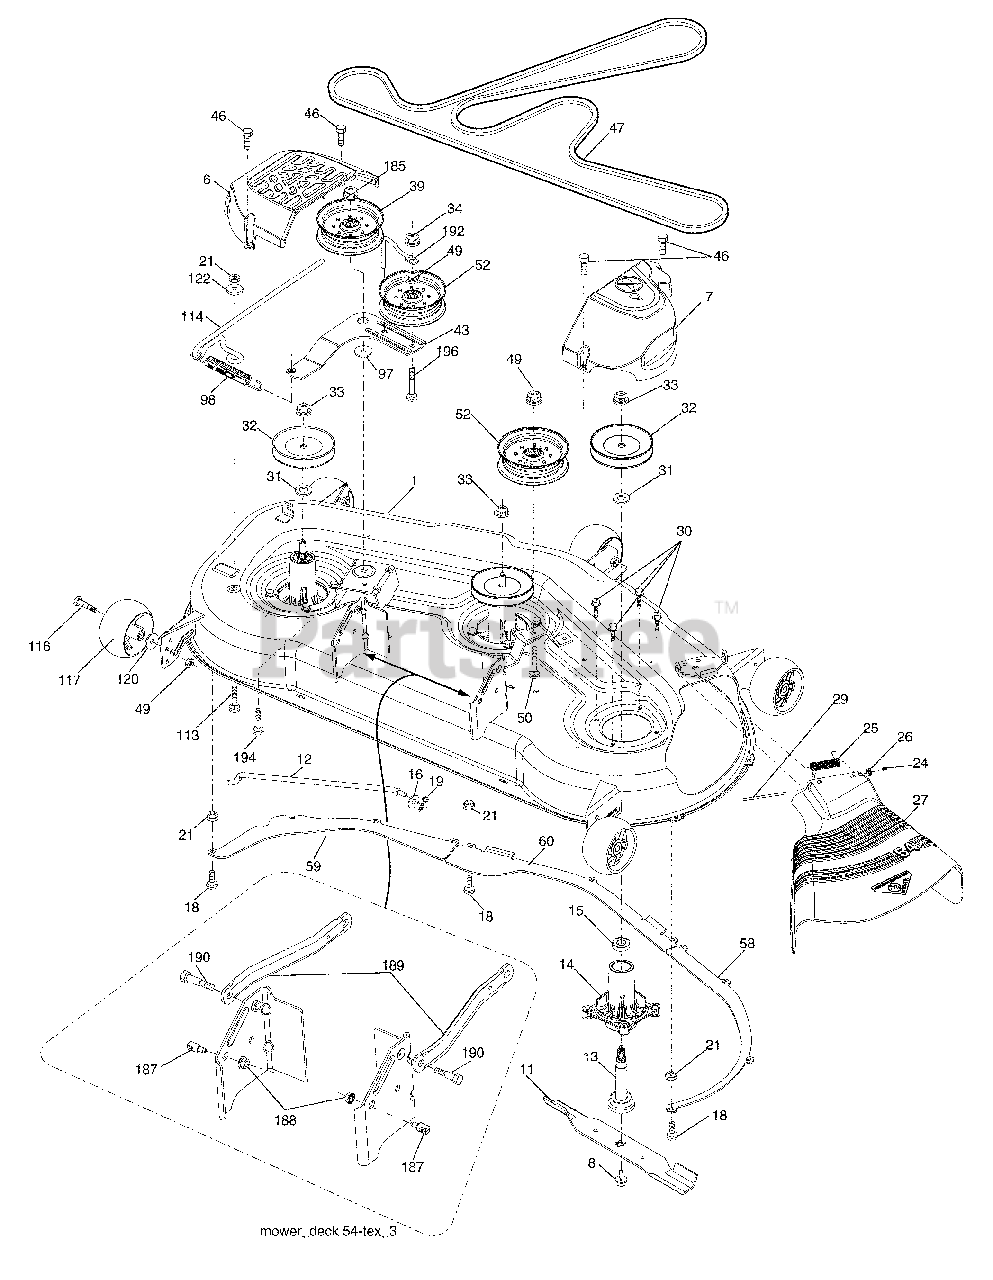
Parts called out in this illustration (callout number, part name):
1	Deck Weldment Mower
6	Cover Mandrel LH
7	Cover Mandrel RH
8	Bolt 7/16 Asm. Blade
11	Blade High Lift
12	Bar Anti-Sway
13	Shaft Asm. w/Lower Bearing
14	Housing, Mandrel
15	Bearing, Ball, Mandrel
16	Washer 3/8
18	Bolt RdHd 5/16-18 unc x 5/8
19	Pin Cotter 5/16 Bowtie
21	Nut, Crownlock 5/16-18 unc
24	Cap Sleeve
25	Spring, Torsion
27	Defl ector Shield
29	Rod, Hinge
30	Screw, Thdroll Washer Head
31	Washer, Spacer Mower Vented
32	Pulley, Mandrel
33	Nut, Flg. Top Lock
34	Nut Crownlock 3/8-46 UNC
39	Pulley, Idler, Stationary LH
43	Arm, Idler
46	Screw, Thdroll. 1/4-20 x 5/8
47	Belt Deck Drive
49	Nut, Lock Flg. 3/8-16 unc
50	Bolt Carriage 3/8-16 x 2 Gr. 5
52	Pulley Idler
58	Baffl e Right
59	Baffl e Left
60	Baffl e Center
97	Washer Hardened
98	Spring Drive
113	Bolt Rdhd Sqnk 5/16-18 x 3/4
114	Rod Tension Relief
116	Bolt, Shoulder
117	Gauge Wheel
120	Washer 13/32 x 1-1/4 x 12 Ga.
122	Bushing Tension Relief
185	Nut Lock Flange 7/16-14 Gr. 5
187	Stud Fastener w/"D" Anti-Rotation
188	Nut Lock Hex Flange
189	Arm Susp. Mower Rear
190	Bolt Shoulder
192	Keeper Belt Idler
194	Bolt Carr Sqnk 7/16-24 x 2
196	Bolt RDHD SQNK 3/8-16 x 2-1/2 Gr.5
